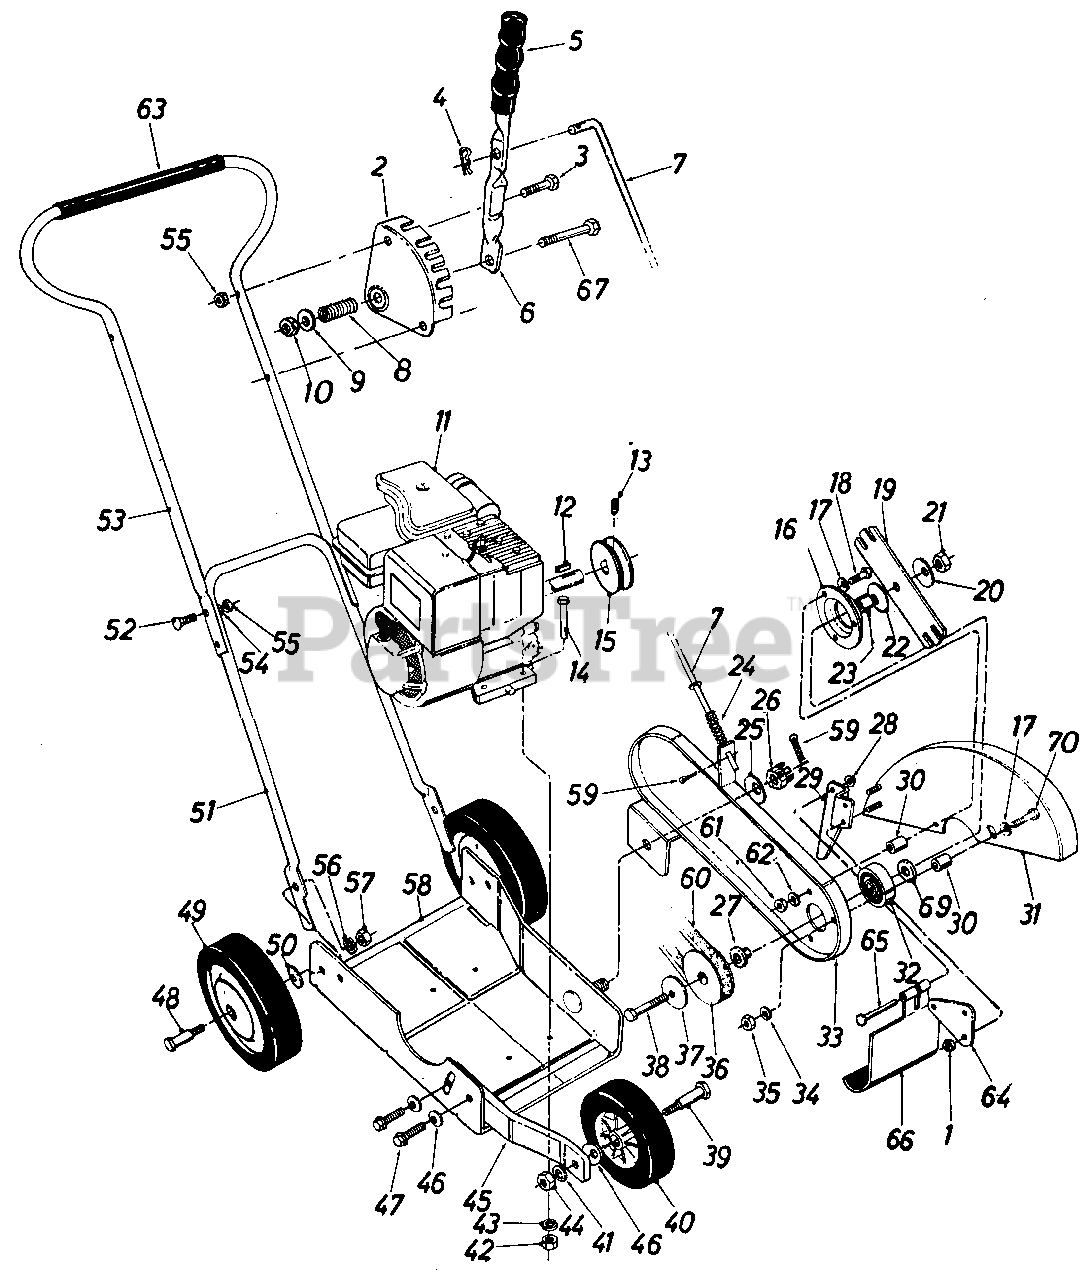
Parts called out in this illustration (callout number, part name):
1	Hex Cent. L.-Nut 1/4-20 Thd.
3	Hex Bolt 1/4-20 x 1.25" Lg.*
4	Cotter Pin 1/8" Dia. x 1.0" Lg.*
5	Grip
6	Clutch Handle
7	Clutch Rod
8	Compression Spring .50" O.D. x 1.38" Lg.
9	Fl.-Wash. 34" I.D. x .62" O.D. x .063
10	Hex Cent. L.-Nut 5/16-18 Thd.
11	Engine
12	Sq.Key 3/16 x 1.0" Lg.*
13	Set Scr. 1/4-28 x 1/4" Lg.
14	Hex Bolt 5/16-18 x 1.50' Lg.*
15	Engine Pulley
16	Bearing Housing
17	Bell.-Wash. .34" I.D. x 88" O.D. x .060
18	Hex Bolt 5/16-18 x 1.25" Lg.*
20	Bell.-Wash. .535" I.D. x 1.50" O.D. x.052
21	Hex Cent. L.-Nut 1/2-20 Thd.
22	Bell.-Wash. .535" I.D. x 1.50" O.D. x .052
23	Spacer
24	Compression Spring .57" O.D. x 1.92" Lg.
25	Bell.-Wash. .535" I.D. x 1.50" O.D. x .052
26	Hex Castle Nut 1/2-20Thd.
27	ShouIder Spacer
28	Push Cap
29	Guide
30	Spacer.354" I.D. x.635" O.D. x .510" Lg.
33	Spindle Bracket Ass'y.
34	L.-Wash. 5/16" I.D.*
35	Hex Nut 5/16-18 Thd.
36	Pulley
37	Bell.-Wash. .535" I.D. x 1.50" O.D. x.052
38	Hex Bolt 1/2-20 x 3.50" Lg.*
39	Shoulder Bolt .498" Dia. x 1 .450
40	WheelAss'y.Comp.6" Dia. x 1.50
41	L.-Wash. 3/8" I.D.*
42	Hex Nut 5/16-18 Thd.*
43	L.-Wash. 5/16" I.D.*
44	Hex Nut 3/8-16 Thd.*
45	Front Wheel Support
46	Bell.-Wash. .400" I.D. x 88" O.D. x.060
47	Hex Wash. Hd. Self Tap Scr. 3/8-16 x .75 " Lg.
48	Shoulder Bolt.498" Dia. x 1.450
49	Wheel Ass'y. Comp. 7" Dia. x 1.50
50	Bell.-Wash. .400" I.D. x 88" O.D.
51	Lower Handle
52	Carriage Bolt 1/4-20 x 1.25" Lg. *
53	Upper Handle
54	L.-Wash. 1/4" I.D. *
55	Hex Nut 1/4-20 Thd.*
56	L.-Wash. 3/8" I.D.*
57	Hex Nut 3/8-16 Thd.
58	Base Ass'y.
59	Cotter Pin 1/8" Dia. x 1.0" Lg. *
60	3V-Belt 31.2" Lg.
61	Hex Nut 5/16-18 Thd.
62	L.-Wash. 5/16" I.D.*
63	Grip (Optional)
64	Flap Bracket
65	Hinge Pin
66	Debris Deflector
67	Hex Bolt 5/16-18 x 1.75" Lg. *
69	Fl.-Wash. .51 I.D. x 1.00 O.D. x .060
70	Hex Bolt 5/16-18 x 2.00" Lg. *
